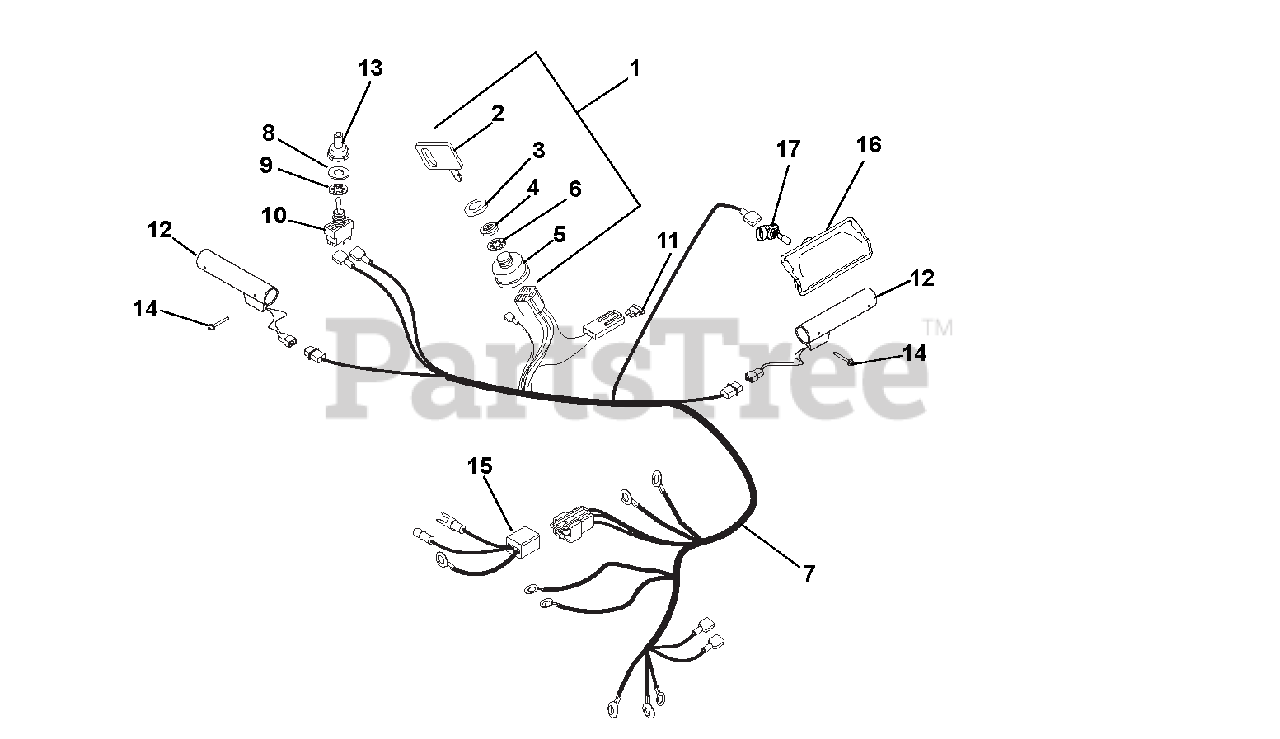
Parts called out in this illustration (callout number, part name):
1	SWITCH ASSEMBLY
2	KEY -W/CAP
3	CAP - IGNITION SWITCH
4	NUT-PANEL .625-32 GRECO
5	IGNITION SWITCH ASSEMBLY
6	WSHR-LK-INT .625X.045 YWZC
7	HARNESS, LIGHT & WARMER
8	WSHR-FL-STL .505X.875X.024 PL
9	WSHR-LK-INT .563X.040 YWZC
10	SWITCH, ON/OFF
11	FUSE, 15 AMP.
12	HEATED GRIP, MAGURA
13	BOOT, SWITCH
14	RVT-POP #43 .125X.313 STL ZINC
15	HARNESS ADAPTER, BRIGGS 12V
16	HEADLIGHT ASSY, HALOGEN 20W
17	BULB, LIGHT-HALOGEN 20W
